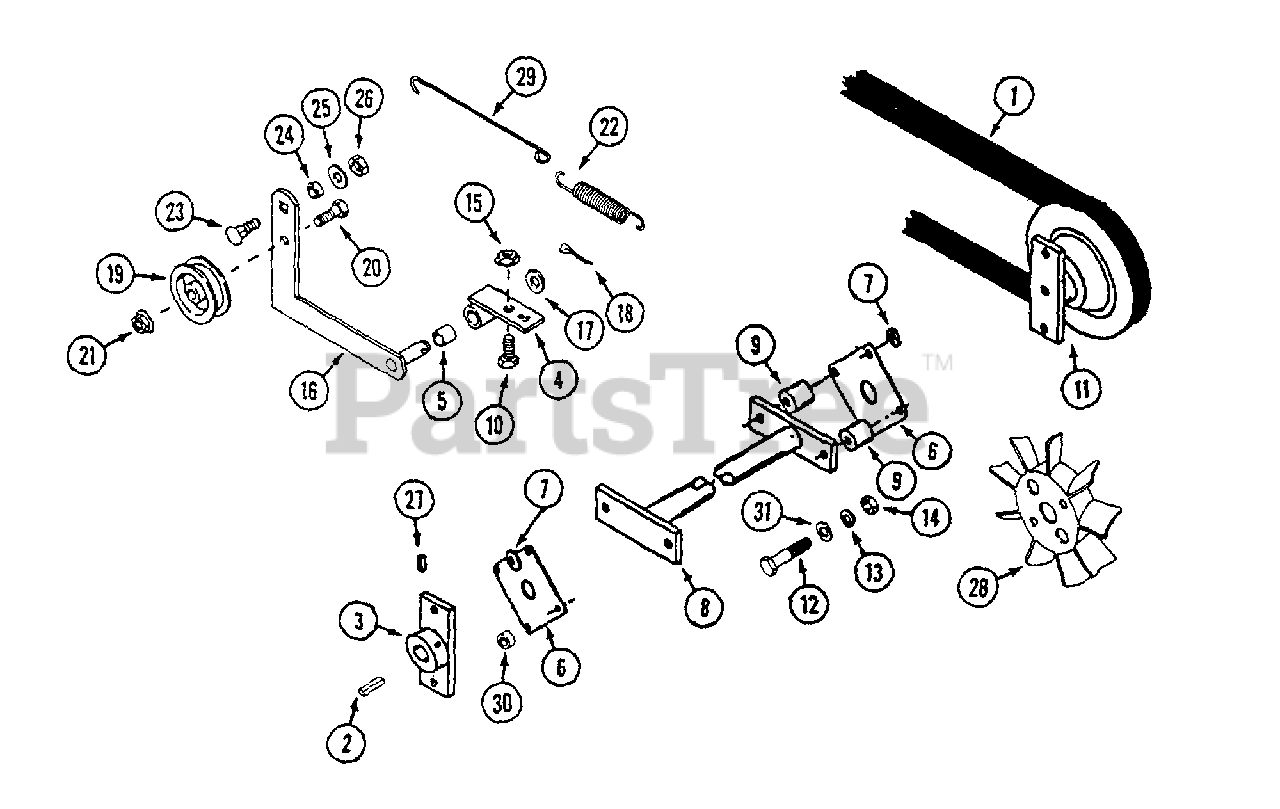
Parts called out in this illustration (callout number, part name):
1	BELT - transmission drive
2	KEY - 5 x 5 x 25 mm
3	HUB - drive plate
4	MOUNT - idler
6	PLATE - drive
7	WASHER - 5/16" 10 ga.
8	SHAFT - cross
10	BOLT - 3/8" - 16 x 1"
11	PULLEY - drive
12	BOLT - 5/16" - 18 x 1"
12	BOLT - 5/16" - 18 x 1-1/4"
12	BOLT - 5/16" - 18 x 2-1/4"
13	LOCKWASHER - 5/16"
14	NUT - 5/16" - 18
15	NUT - 3/8 - 16 flange lock
17	WASHER - 1/2" x 7/8"
18	PIN - cotter - 1/8" x 1"
19	PULLEY - idler
20	BOLT - 3/8" - 16 x 1-1/2"
21	NUT - 3/8" - 16 flange lock
22	SPRING - tension
23	BOLT - carriage 3/8" - 16 x 1"
24	SPACER - 3/8" x 1/2"
25	WASHER - 3/8"
26	NUT - 3/8" - 16 lock
27	SETSCREW - 5/16" - 18 x 5/16"
28	FAN - CCW L.H. Side
28	FAN - CCW R.H. Side
29	LINK - idler spring
30	SPACER - 1/4"
31	WASHER - 5/16"
